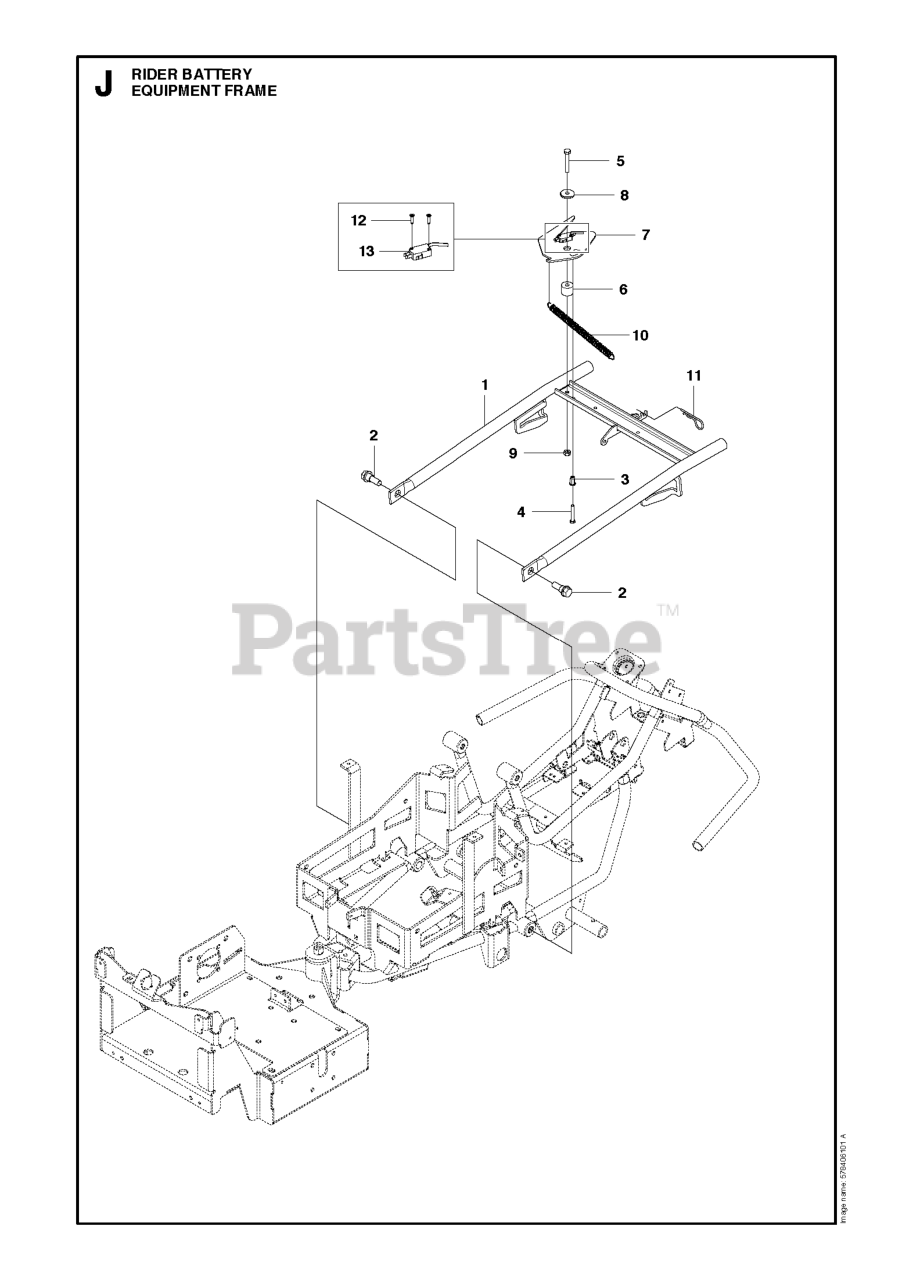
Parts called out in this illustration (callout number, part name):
8	WASHER
9	LOCKNUT M8
13	MICRO SWITCH
